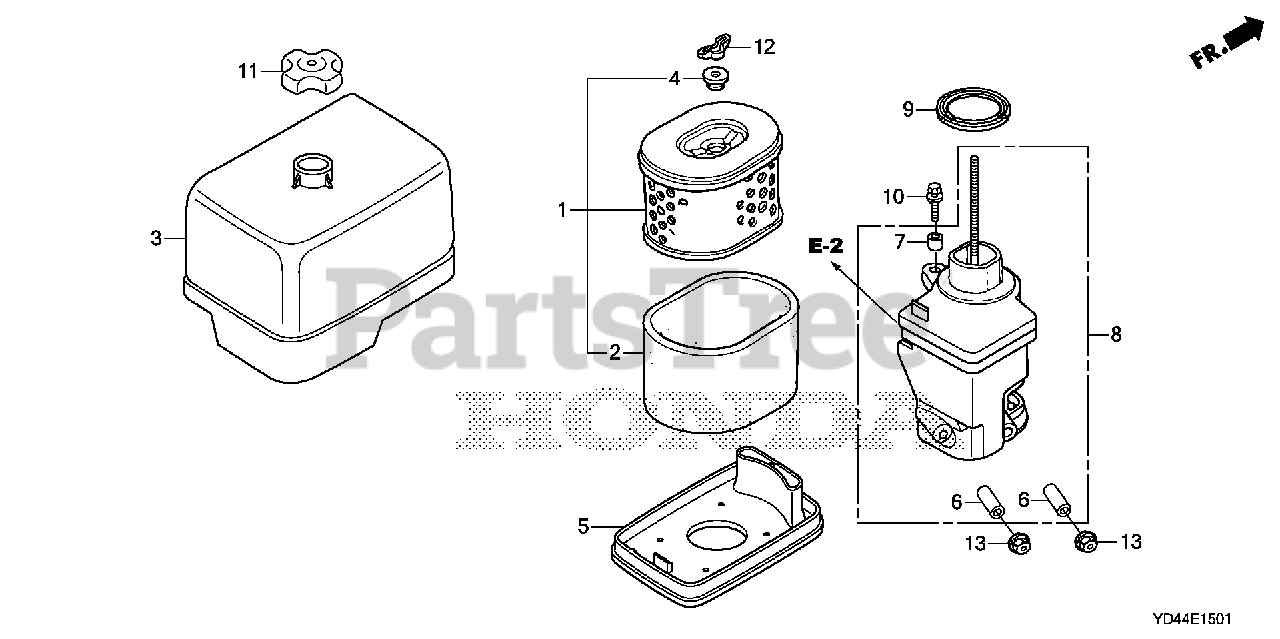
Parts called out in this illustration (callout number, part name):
1	ELEMENT, AIR CLEANER
2	FILTER (OUTER)
3	COVER, AIR CLEANER HOUSING
4	GROMMET, AIR CLEANER
5	NOSE, MUFFLER
6	COLLAR, AIR CLEANER
7	COLLAR B, AIR CLEANER
8	ELBOW, AIR CLEANER
9	GASKET, AIR CLEANER HOUSING
10	BOLT-WASHER (6X22)
11	NUT, AIR CLEANER COVER
12	WINGNUT, TOOL BOX SETTING
13	NUT, FLANGE (6MM)
